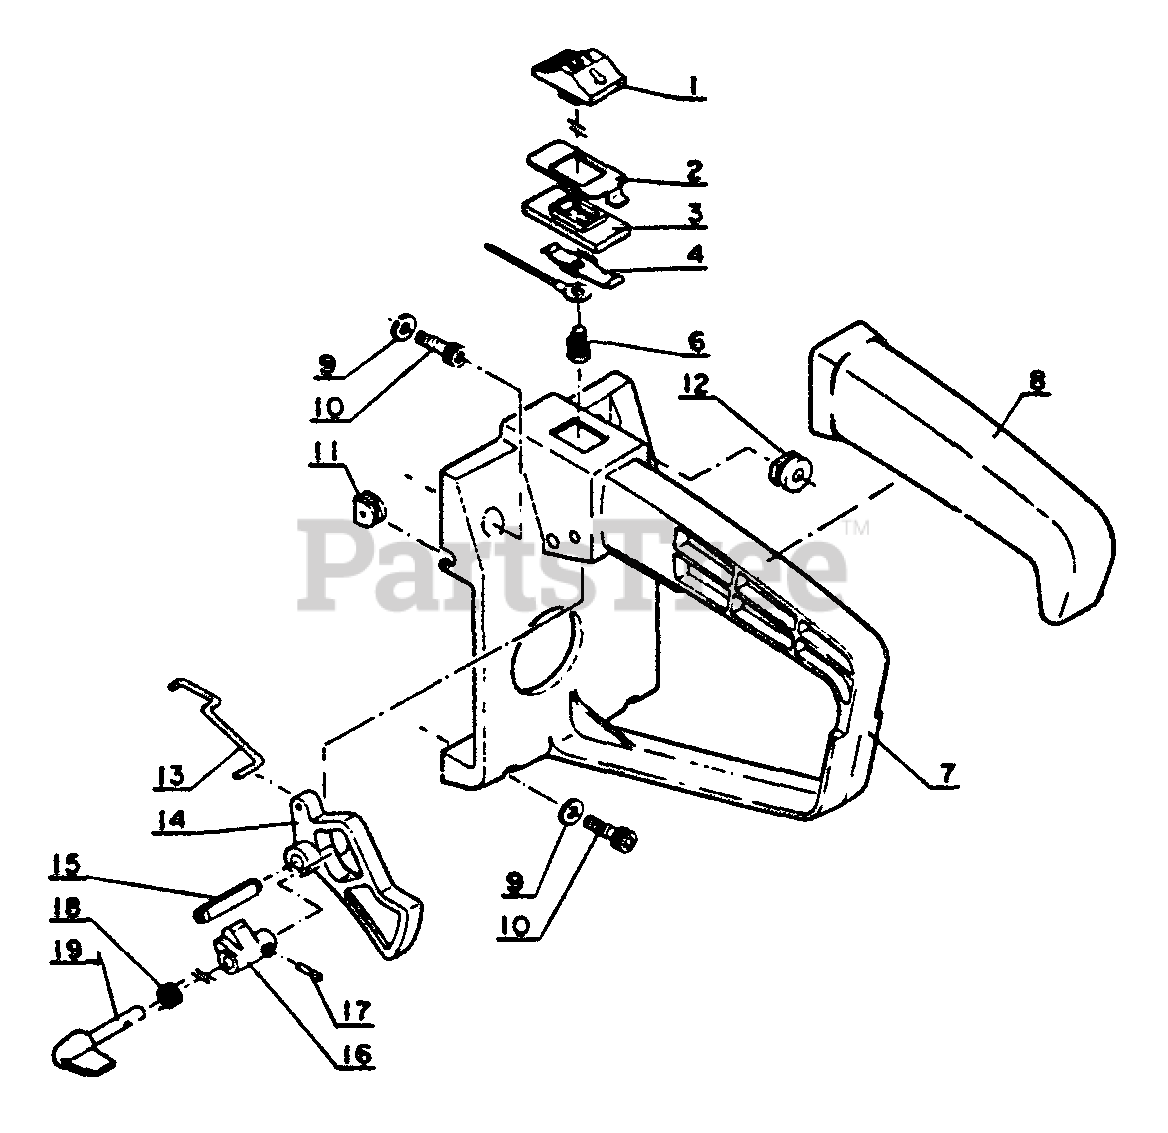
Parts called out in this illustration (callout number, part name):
1	KNOB, SWITCH
2	PLATE - GROUND
3	GUIDE, SWITCH
4	CONTACT, SWITCH
6	SCREW - 4X10
7	HANDLE - REAR
8	GRIP
9	WASHER - 4
10	SCREW - 4X18
13	ROD, THROTTLE
14	TRIGGER, THROTTLE
15	PIN - SPRING -- 5X25
16	LOCKOUT, THROTTLE
17	PIN - SPRING -- 1.6X10
18	SPRING, LOCKOUT LEVER
19	LEVER, THROTTLE
